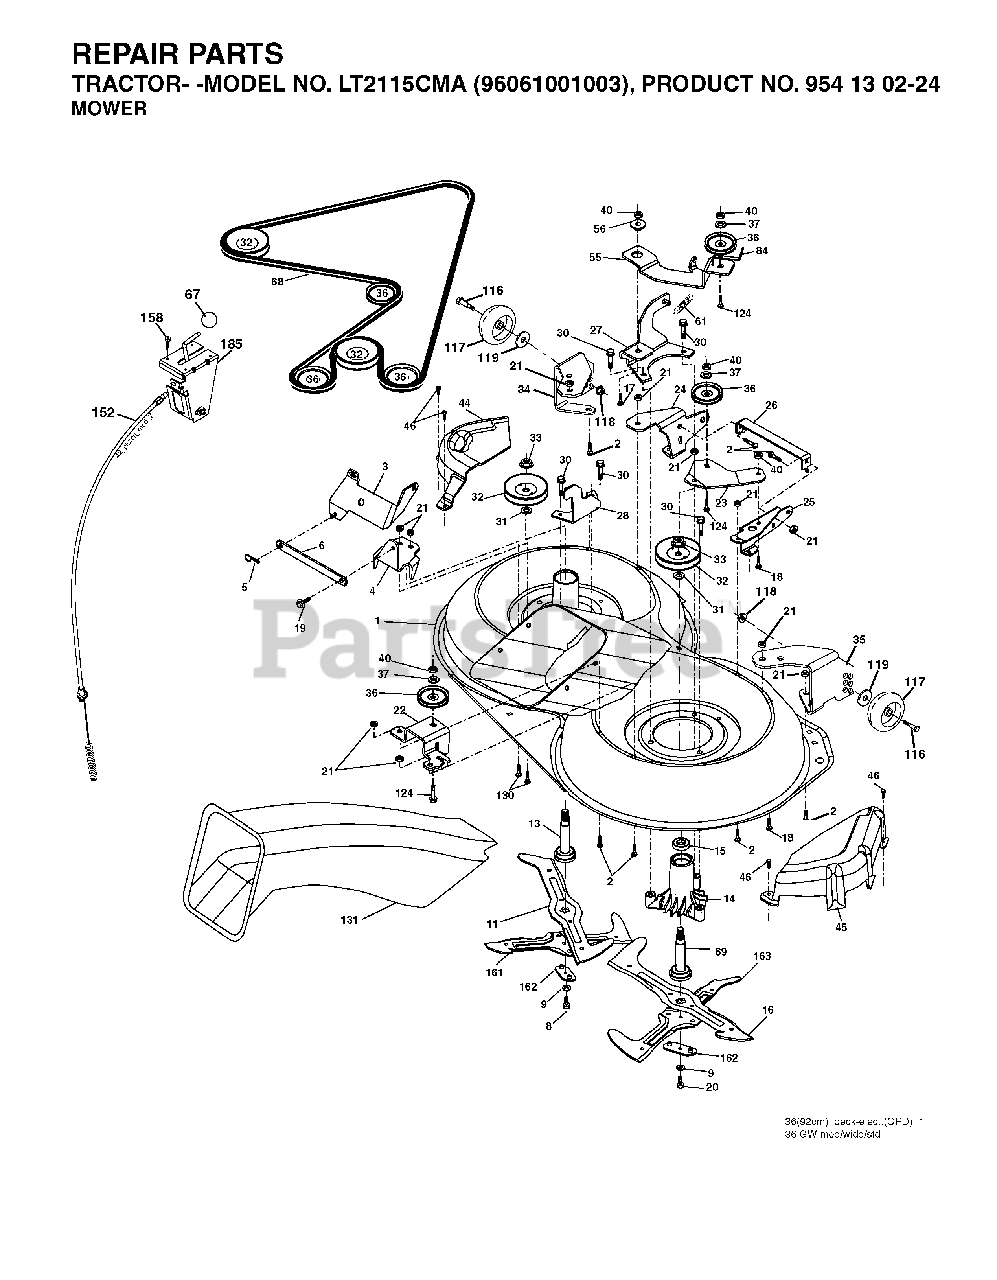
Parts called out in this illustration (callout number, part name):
1	MOWER HOUSING, DECK
2	BOLT
3	BRACKET
5	RETAINER-SPRNG RB
6	BAR SWAY
9	LOCKWASHER
13	SHAFT ASM VENT
14	HSG MANDREL
17	BOLT.3/8-14X1.25
19	BOLT SHD 5/16-18
21	LOCKNUT
24	BRACKET
25	BRACKET
26	BRACE
28	BRACKET
30	SCREW, WASHER HEAD
31	WASHER.SPACER.MANDREL
32	PULLEY, MANDREL
33	NUT, FLG TOPLOCK 9/16"
36	PULLEY.IDLER.4.25
40	LOCKNUT
45	MANDREL COVER
46	SCREW.1/4-20X5/8
55	ARM IDLER
56	SPACER.RETAINER.MOWER
61	SPRING.TENSION.BELT
67	KNOB T (3/8 HOLE)
68	HEX-BELT
69	SHAFT.ASM.W/LWR.BRG.RH.THREAD
84	KEEPER, BELT IDLER
116	SHOULDER BOLT
117	WHEEL. GUAGE RALLY
118	LOCKNUT
119	WASHER
124	BOLT.3/8-16X1.50
131	CHUTE BAGGER
158	SCREW
185	HEAD ASM. CABLE CLUTCH
